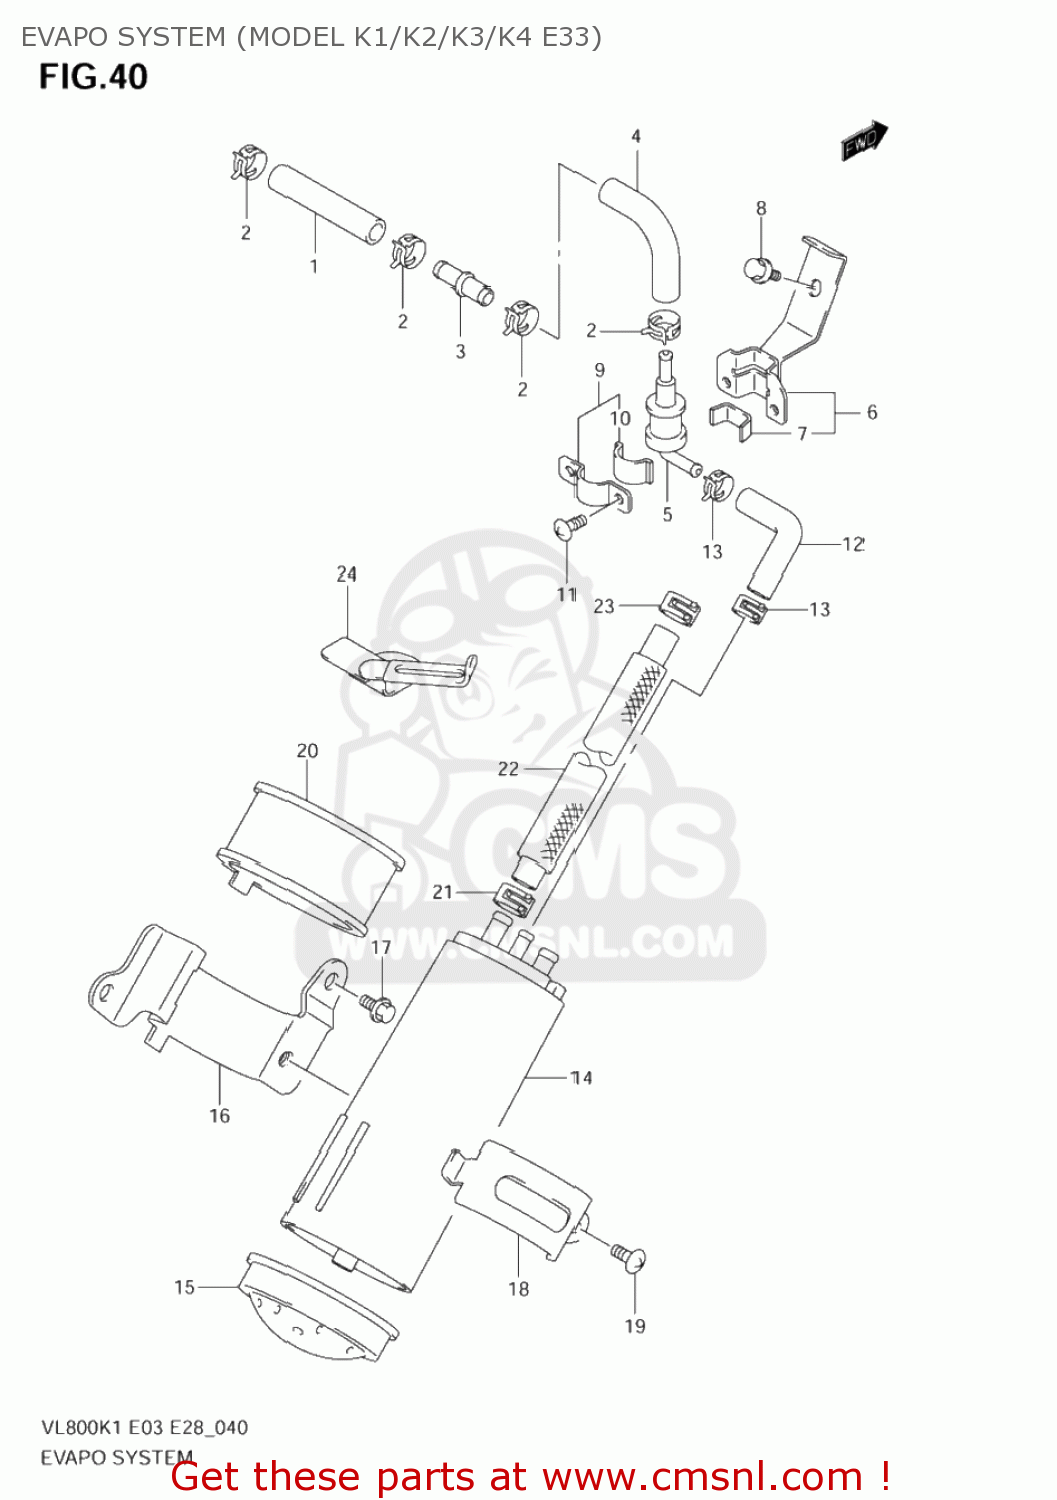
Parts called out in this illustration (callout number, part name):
1	HOSE,TANK & BREATHER VALVE UP
2	CLIP
3	JOINT
4	HOSE, TANK & VALVE LOWER
5	VALVE,FUEL TANK BREATHER
6	BRACKET,FUEL TANK BREATHER
7	CUSHION
8	BOLT
9	PLATE,FUEL TANK BREATHER NO.2
10	CUSHION
11	SCREW
12	HOSE,BREATHER VALVE & CANISTER
13	CLIP
14	CANISTER ASSY,CHARCOAL
15	CAP,CANISTER
16	BRACKET,CANISTER
17	BOLT
18	HOLDER,CANISTER
19	SCREW 6X10
20	CUSHION,CANISTER
21	CLIP
22	HOSE,CANISTER & CARB
23	CLIP
24	CLAMP,EVAPORATOR HOSE
